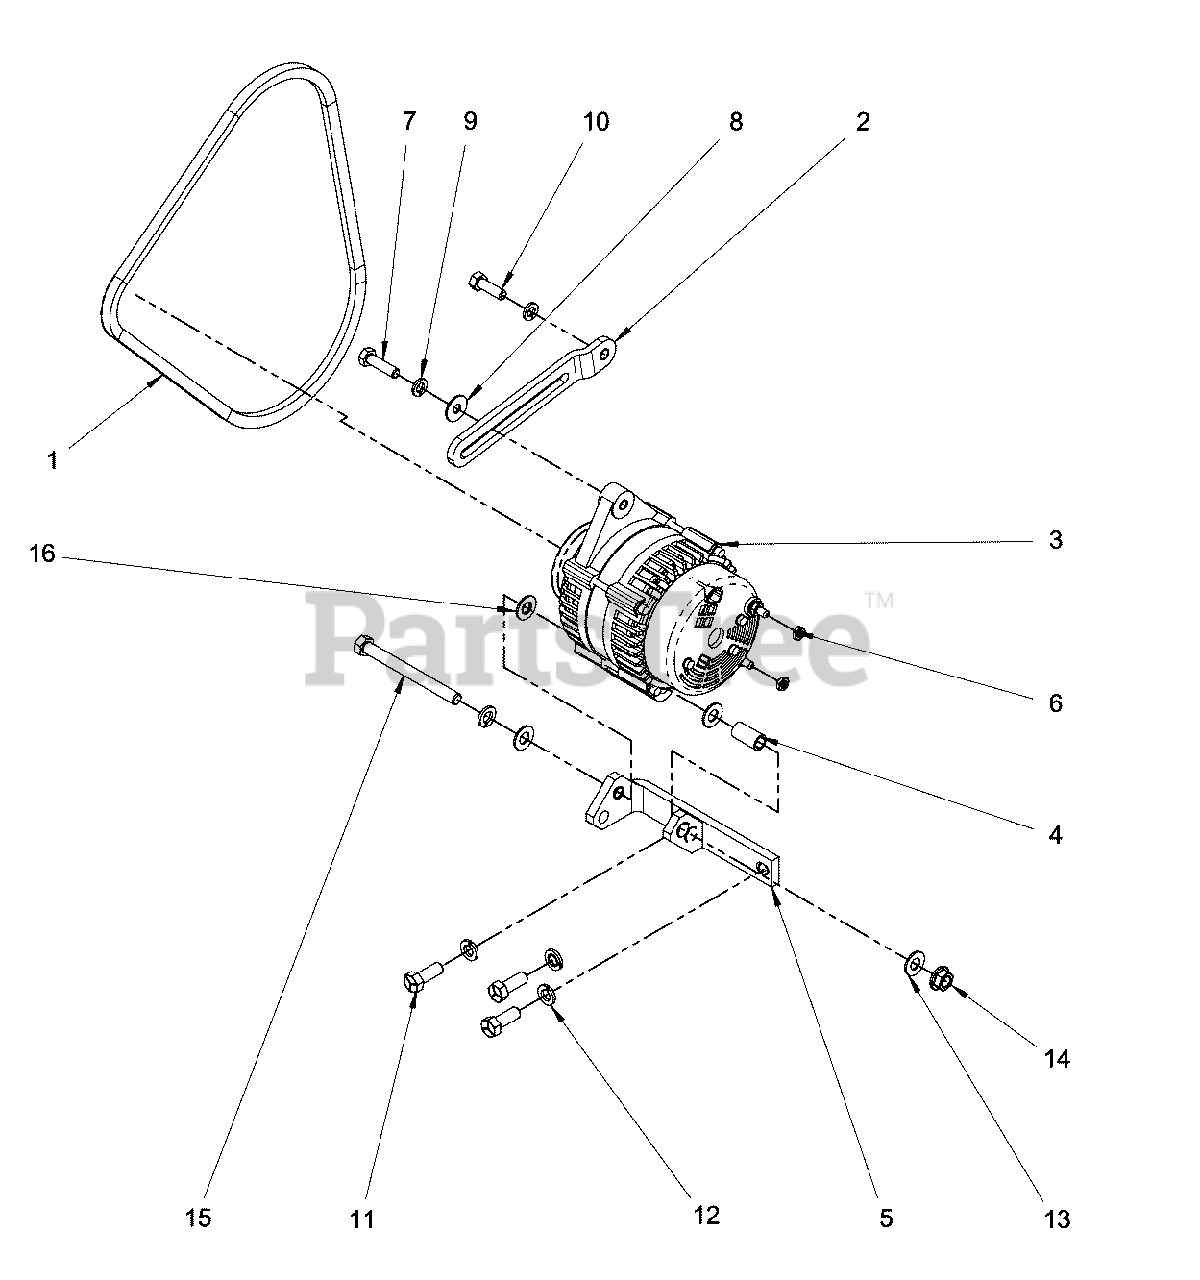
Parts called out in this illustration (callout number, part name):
2	* STRAP
4	* SLEEVE
5	* BRACKET
6	* NUT
7	* BOLT
8	* WASHER
9	* WASHER
10	* BOLT
11	* BOLT
12	* WASHER
13	* WASHER
14	* NUT
15	* BOLT
16	* WASHER
